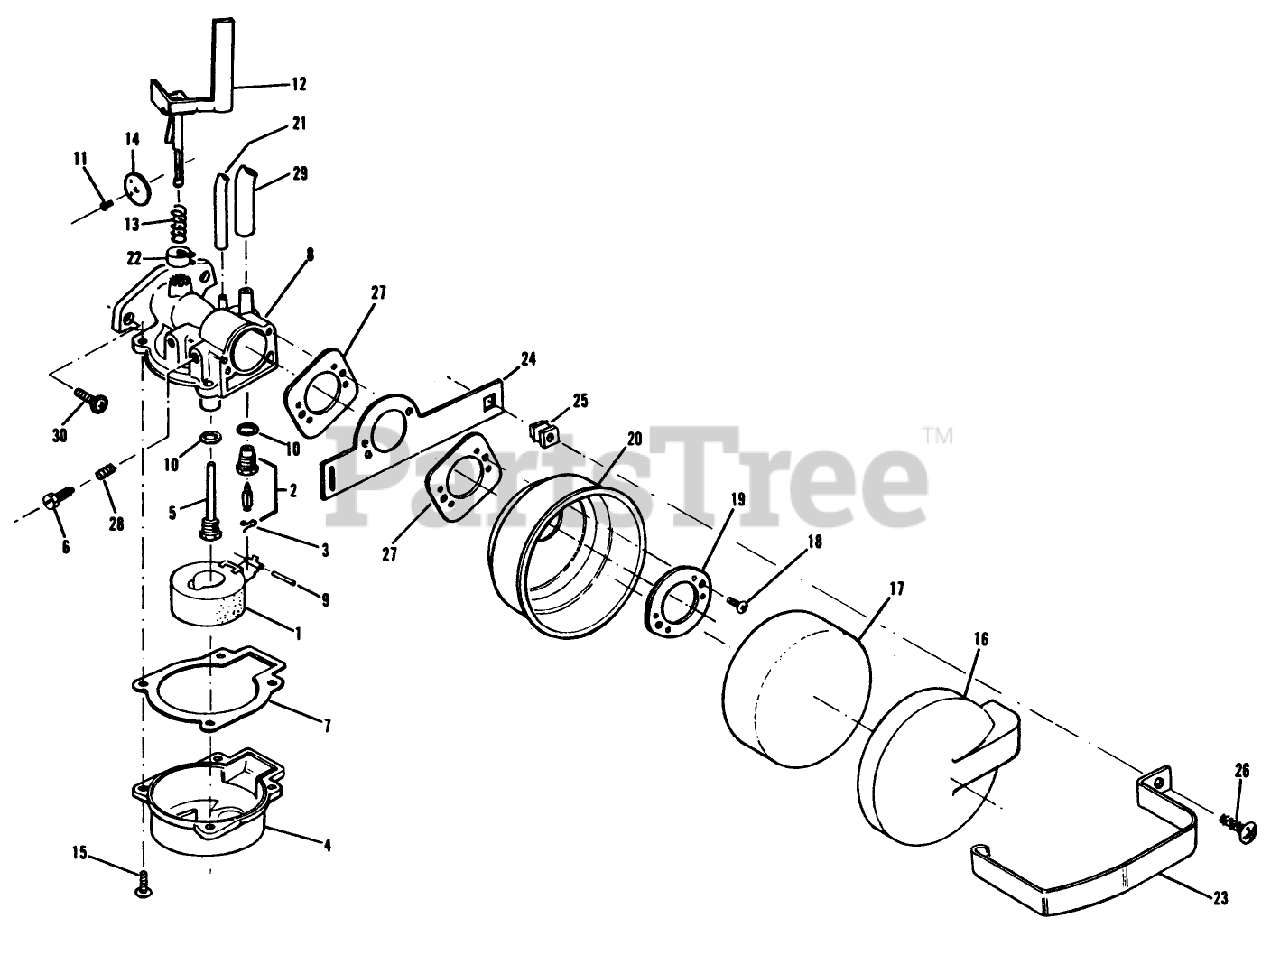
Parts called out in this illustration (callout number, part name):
6	SCREW S
11	SCREW F
17	AIR FIL.ELEM S
18	SCREW S
19	WASHER S
21	TUBING PRIMER S
22	CLAMP-SPR ADJ S
23	STRAP S
25	NUT-CLIP
26	SCREW S
27	GASKET S
28	SPRING S
